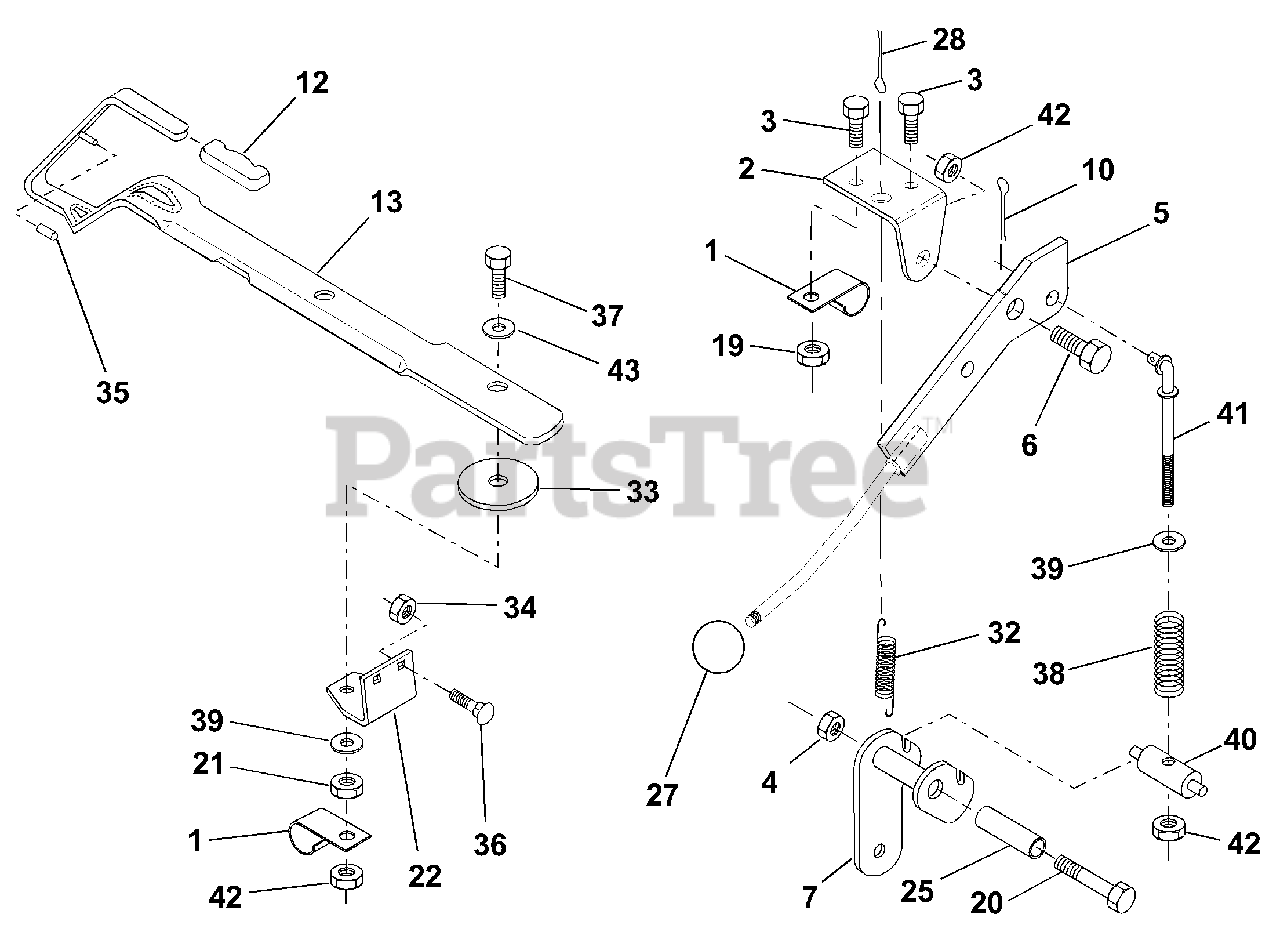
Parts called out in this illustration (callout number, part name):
1	Clip, Insulated
2	Bracket, Mower Clutch
3	Bolt, Hex Hd, Fin. 1/4-20 UNC x 1/2 Grade 5
4	Nut Crownlock 3/8-16
5	Assembly, Clutch Lever
6	Bolt, Shoulder
7	Assembly, Mower Clutch Arm
10	Pin, Cotter 1/8 x 3/4
12	Handle, Lift Lever
13	Assembly, Lift Handle
19	Nut, Crownlock 1/4-20
20	Bolt, Hex Hd, Fin. 3/8-16 UNC x 2-3/4
21	Nut, Centerlock 3/8-16 UNC
22	Bracket, Lift Lever
23	Pin, Cotter 3/32 x 3/4
25	Tube, Spacer
32	Spring, Extension, Return
33	Washer .390 x 1.437 x .074
34	Nut, Lock Hx w/Ins 5/16-18
35	Cap, Vinyl, Red
36	Bolt, Carriage 5/16-18 x 3/4
37	Bolt, Hex Head 3/8-16 UNC x 1-1/2
38	Spring, Compression
39	Washer 13/32 x 1 x 11 Gauge
40	Trunnion, Threaded 3/8-16
41	Rod, Tension, Clutch
42	Nut Lock Hex w/wsh 3/8 - 16
43	Washer 25/64 x 1-1/4 x 12 Gauge
